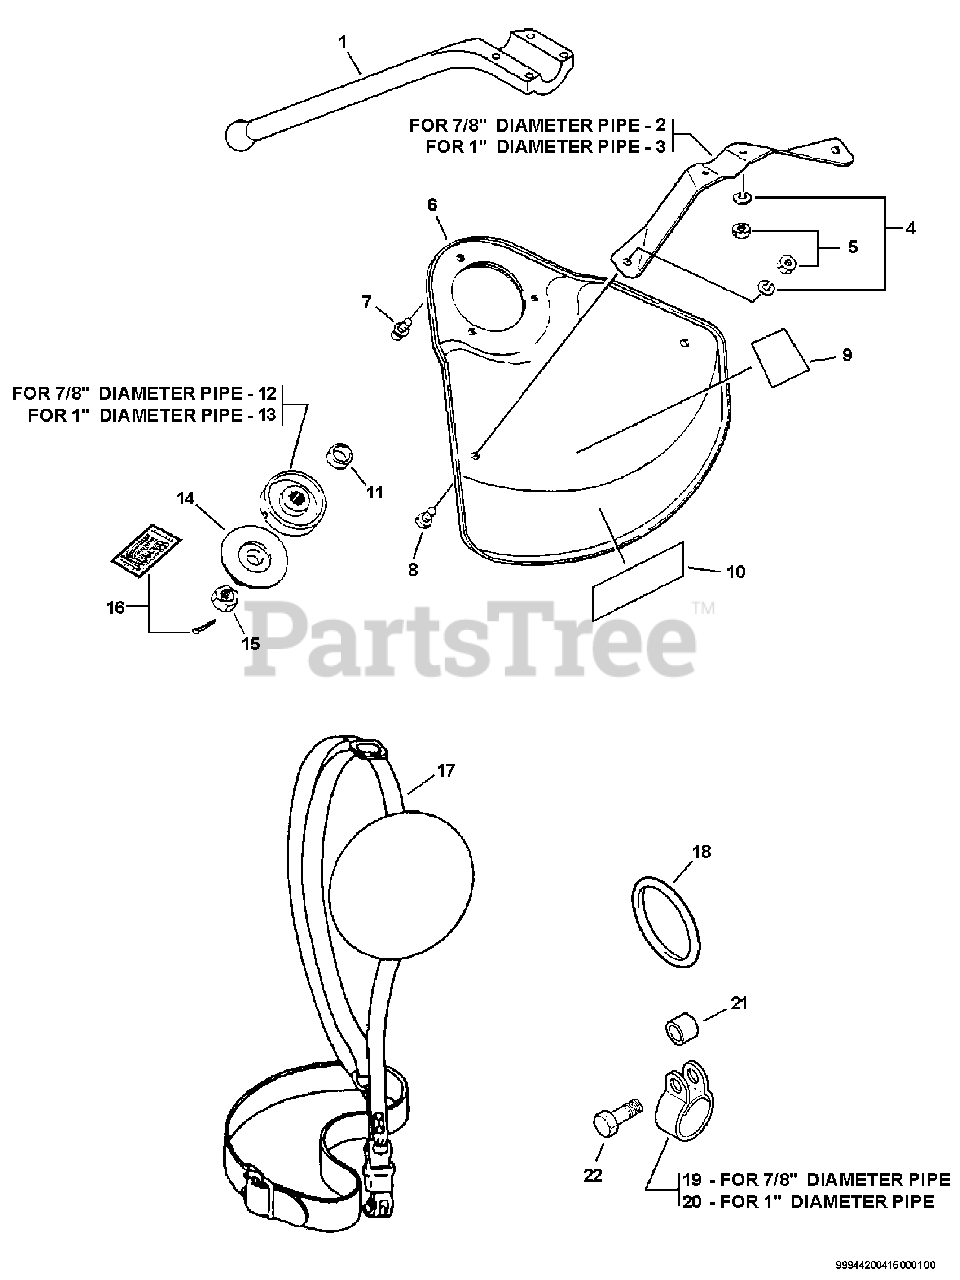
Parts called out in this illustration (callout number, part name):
1	BAR, BARRIER
2	BRACKET, SHIELD
3	BRACKET, SHIELD
4	LOCKWASHER - 5
6	SHIELD, DEBRIS - METAL
7	SCREW - 5X10
8	SCREW - 5X8
9	LABEL - DANGER
10	LABEL - ECHO
12	ADAPTOR, BLADE - UPPER
13	ADAPTOR, BLADE - UPPER
14	ADAPTOR, BLADE - LOWER
15	NUT - 10 -- LEFT HAND
16	PIN, SPLIT - 2X22
17	HARNESS ASSY
19	CLAMP
20	HOOK
22	BOLT - 5X18
